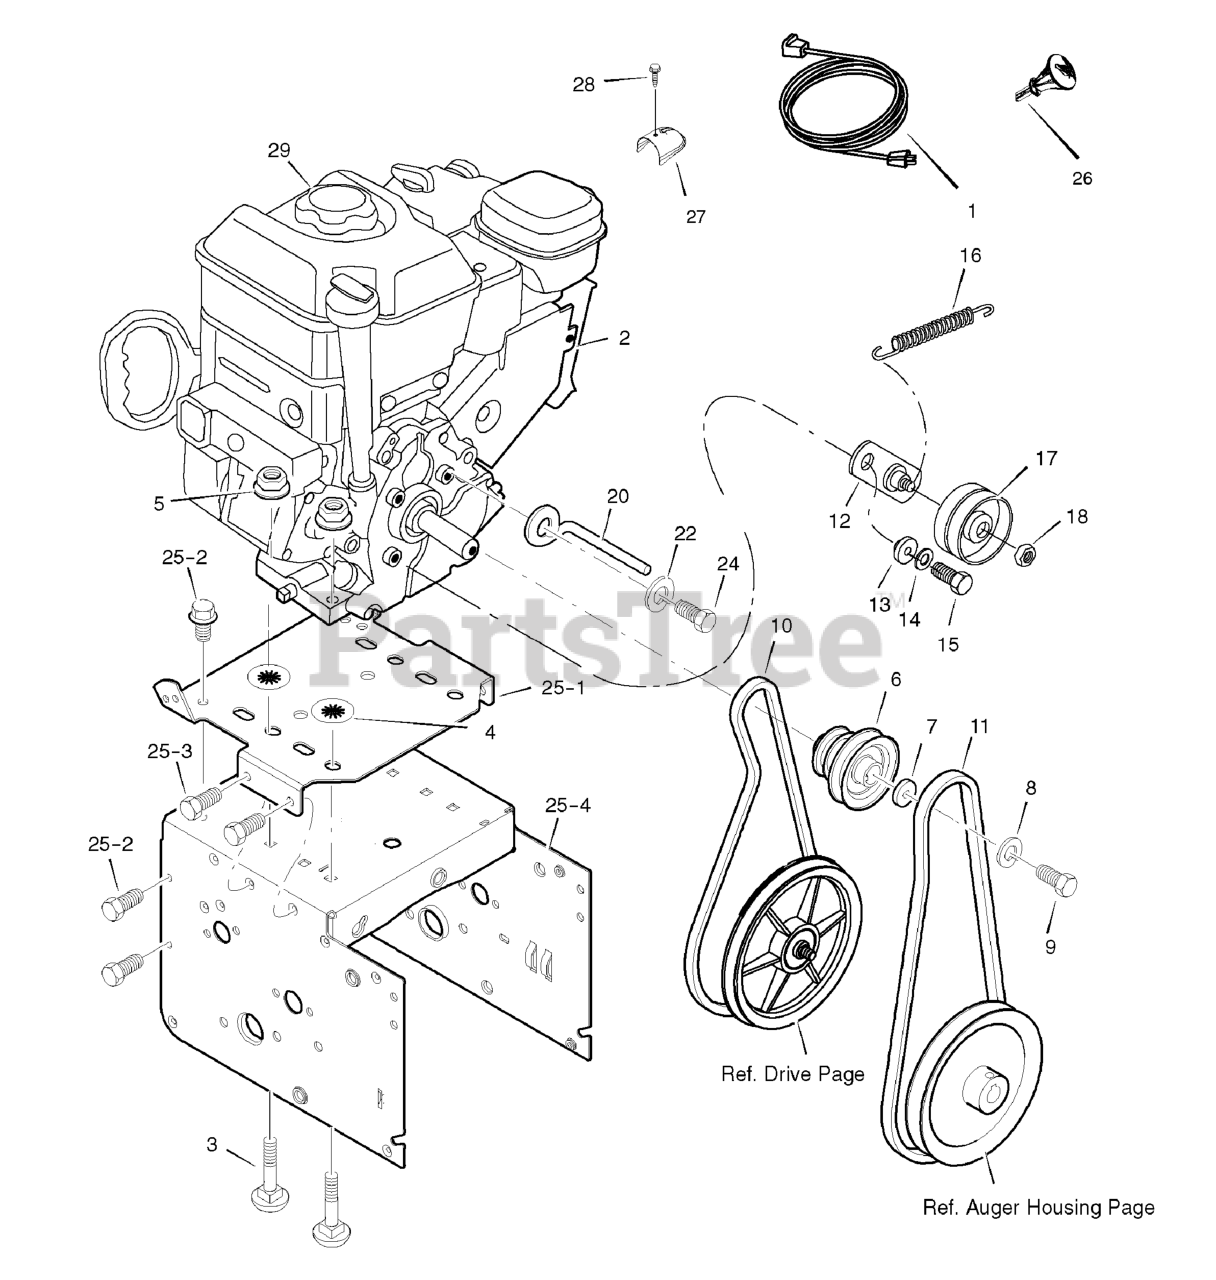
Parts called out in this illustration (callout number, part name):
1	CORD, Electric, 10FT. 110V
3	BOLT, CARRIAGE 5/16-18
4	RETAINER, PUSH
5	NUT 5/16-18
6	PULLEY, ENGINE
8	WASHER
9	SCREW, .37-24 X 1.00
10	BELT, V 3L
11	BELT, V 4L
12	BRACKET ASSEMBLY, IDLER
13	BUSHING, IDLER BRACKET
14	WASHER
15	SCREW 5/16-24 X 0.75
17	PULLEY, IDLER
18	NUT, JAM 3/8-16
20	GUIDE, ROD BELT
22	WASHER, SPTLK .31 X .58 X .08
24	SCREW, 5/16-24 X 0.75
25	FRAME ASSEMBLY
25-1	PLATE, ENGINE MOUNT
25-2	SCREW 1/4-20 X .63
25-3	SCREW 5/16-18 X .50
25-4	FRAME, MOTOR BOX
26	KEY, IGNITION
27	DEFLECTOR, MUFFLER
29	GAP CAP, WITH GAUGE
